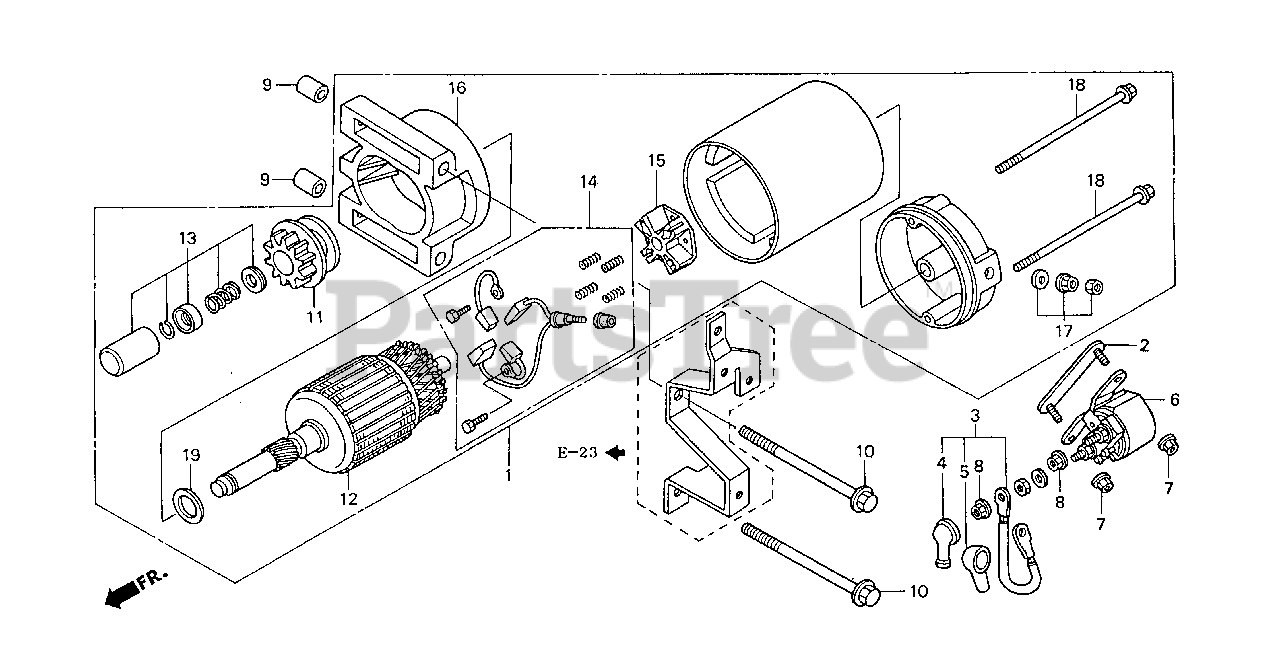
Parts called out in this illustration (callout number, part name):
1	MOTOR ASSY., STARTER
2	BRACKET, STARTER MAGNETIC SETTING
3	CABLE, MAGNET SWITCH
4	COVER A, MAGNETIC SWITCH
5	COVER, STARTER MOTOR TERMINAL
6	SWITCH ASSY., STARTER MAGNETIC
7	NUT, FLANGE (6MM)
8	NUT-WASHER (6MM)
9	PIN, DOWEL (10X12)
10	BOLT, FLANGE (8X110)
11	GEAR SET, PINION
12	ARMATURE
13	STOPPER SET, PINION
14	BRUSH SET
15	HOLDER, BRUSH
16	BRACKET, FR.
17	NUT SET, TERMINAL
18	BOLT, THROUGH
19	WASHER, THRUST
